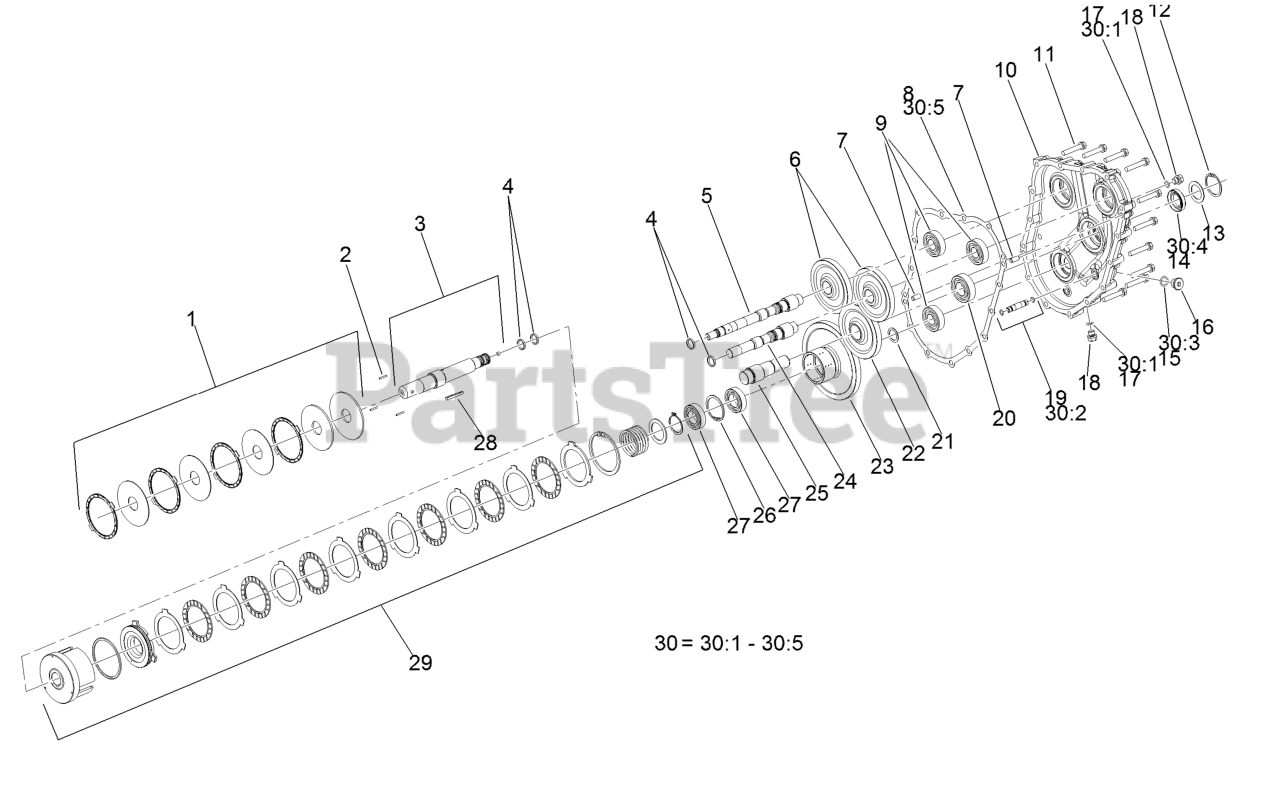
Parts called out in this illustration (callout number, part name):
1	PTO Brake ASM
2	Rod-Push
3	PTO Shaft ASM
4	Ring-Seal
5	Shaft-Pump
6	Gear-Pump
7	Pin-Parallel
8	Gasket-Housing, Gear
9	Bearing
10	Housing-Case, Gear
12	Ring-Snap
15	Packing
16	Plug-NPTF
17	O Ring-Plug
20	Bearing
22	Gear-Input
23	Gear-PTO
24	Shaft-Pump
25	Shaft-Input
26	Ring-Snap
27	Bearing
29	Clutch Cylinder ASM
30	Gear Housing Seal Kit
30:1	O Ring-Plug
30:2	O-Ring
30:3	Packing
30:5	Gasket-Housing, Gear
